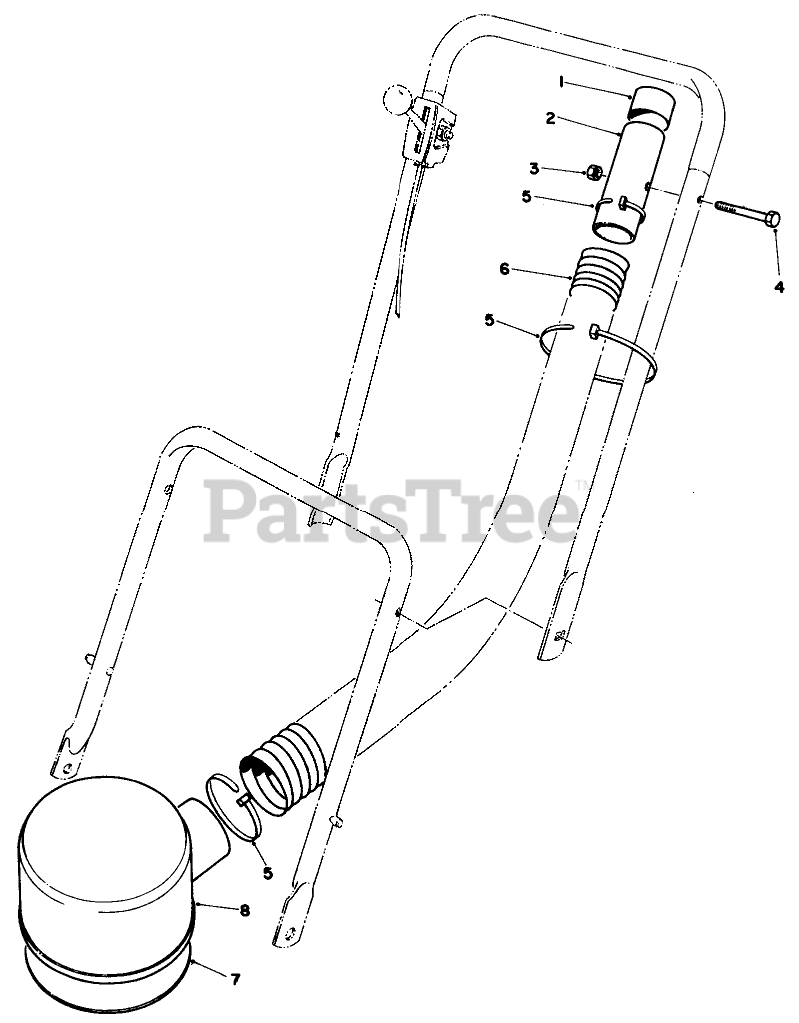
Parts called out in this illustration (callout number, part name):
1	BLACK CAPLUG
2	AIR CLNR HOSE TIP
3	NUT-LOCK, CONE
4	NUT-LOCK, CONE
5	TIE-CABLE
6	AIR CLEANER HOSE
7	AIR CLEANER BASE
8	Air Cleaner Cover
